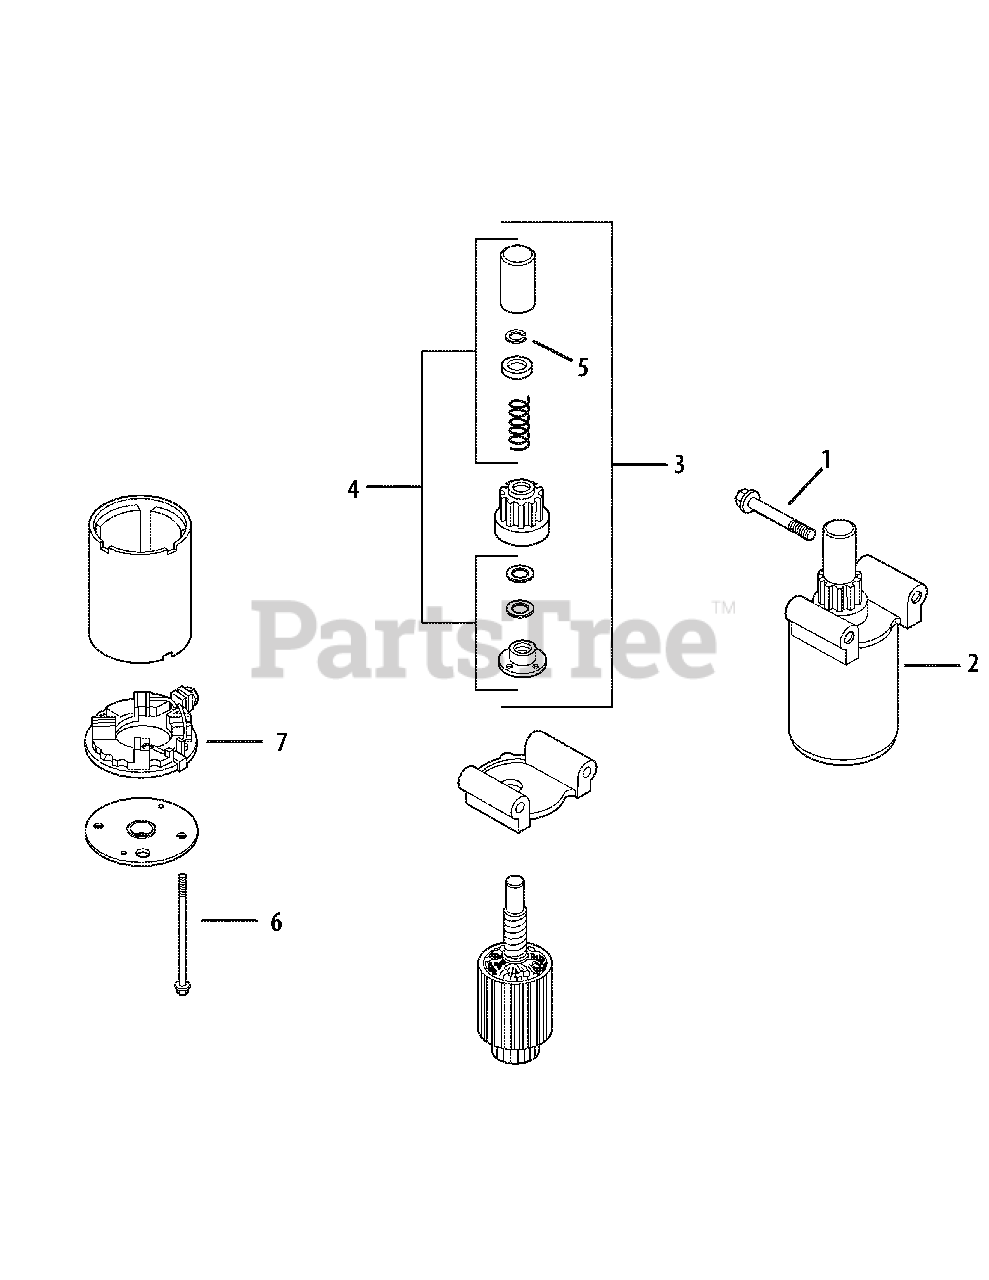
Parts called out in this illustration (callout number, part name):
1	Screw, hex. flange M8x1.25x70
2	Starter assembly
4	Kit, drive parts
5	Retaining Ring
7	Commutator, end cap
